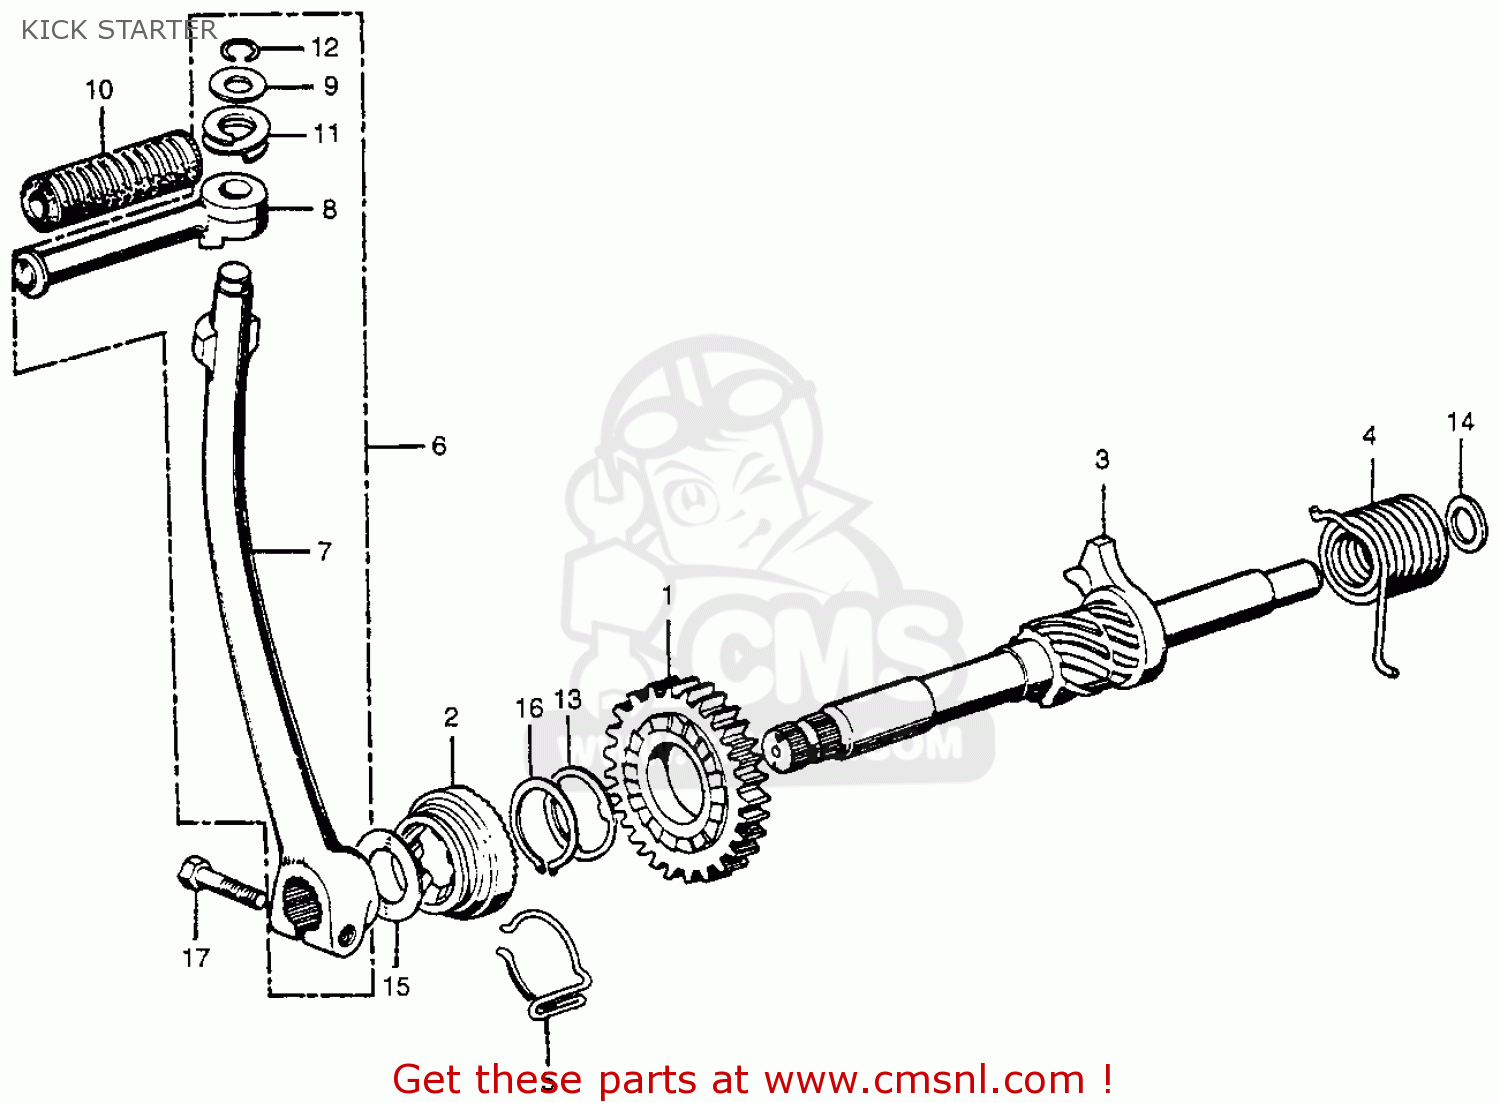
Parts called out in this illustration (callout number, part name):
1	PINION,STARTER
2	RATCHET,DRIVE
3	SPINDLE,STARTER
4	SPRING,STARTER
5	SPRING,FRICTION
6	ARM,KICK STARTER
7	ARM,KICK STARTER
8	PEDAL, STARTER
9	WASHER
10	RUBBER,STATOR
11	SPRING
12	CLIP
13	WASHER,THRUST
14	WASHER,THRUST
15	WASHER,THRUST
16	CIRCLIP 22.5M/M
17	BOLT,HEX 6X20
